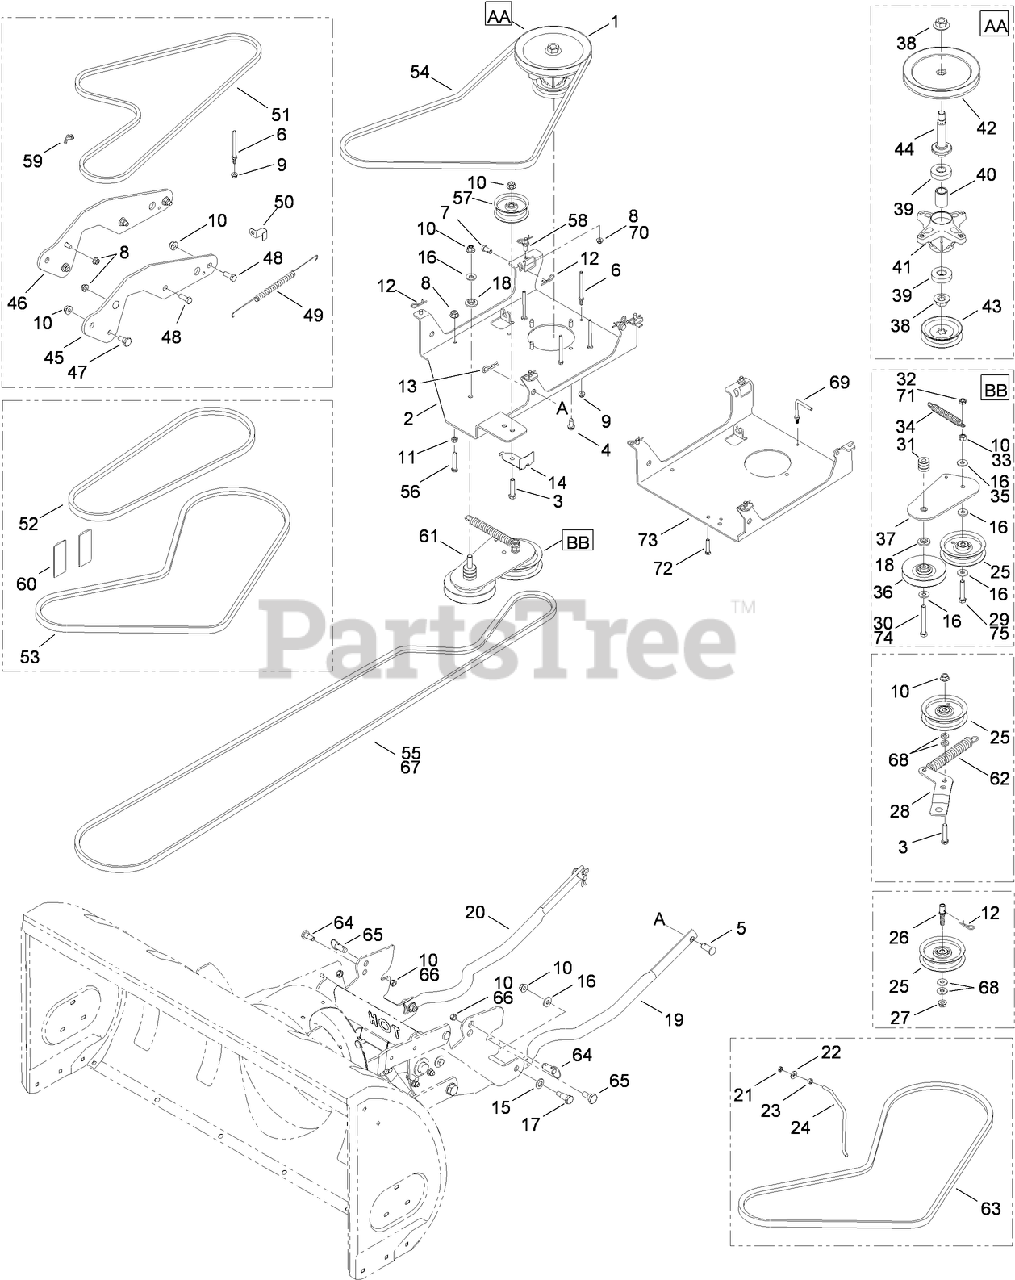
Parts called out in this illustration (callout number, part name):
1	7 INCH PULLEY SPINDLE ASM
2	BRACKET-MOUNTING, PULLEY
3	SCREW-HH
4	SCREW-HWH
5	PIN-CLEVIS
6	KEEPER-BELT
7	PIN-CLEVIS
8	NUT-LOCK, FLANGE
9	NUT-LOCK, FLANGE
10	NUT-LOCK, FLANGE
11	NUT-HEX
12	PIN-CLICK
13	PIN-CLIP, INTERNAL
14	KEEPER-BELT
15	WASHER-FLAT
16	WASHER-ISOMOUNT
17	BOLT-SHOULDER
18	SPACER-SHOULDER
19	TUBE-SUPPORT, LH
20	TUBE-SUPPORT, RH
21	NUT-HEX, JAM
22	WASHER-SPRING
23	NUT-HEX
24	ROD-KEEPER, BELT
25	PULLEY-IDLER, 3.50 INCH
26	SPACER-IDLER
27	NUT-LOCK, FLANGE
28	BRACKET-IDLER
29	SCREW-HH
30	SCREW-HH
31	SPACER
32	NUT-NYLON, JAM
33	NUT-HEX
34	SPRING-EXTENSION
35	WASHER-LOCK
36	PULLEY
37	IDLER PIVOT ASM
38	NUT-LOCK, FLANGE
39	BEARING-BALL
40	SPACER
41	HOUSING-SPINDLE, DECK
42	PULLEY-DECK, 7 INCH
43	PULLEY-3.75 INCH
44	SHAFT-SPINDLE
45	LH BRACKET ASM
46	RH BRACKET ASM
47	BOLT-SHOULDER
48	SCREW-HH
49	SPRING-EXTENSION
51	BELT- V TYPE
52	BELT-V, A SECTION
53	BELT-V TYPE
54	BELT-V
55	BELT-V TYPE
56	BOLT-HH
57	PULLEY-IDLER, FLAT
59	NUT-WING
60	REFLECTOR
61	DOUBLER IDLER BRACKET ASM
62	SPRING-EXTENSION
63	V-BELT, B SECTION
64	BOLT-SHOULDER
65	PIN-RELEASE, QUICK
66	NUT-LOCK
67	BELT-V
68	WASHER-FLAT
69	PIN-KEEPER, BELT
70	NUT-HEX, CENTER LOCK
72	SCREW-HH
73	BRACKET-MOUNTING, PULLEY
74	BOLT-HEX
75	SCREW-HH
